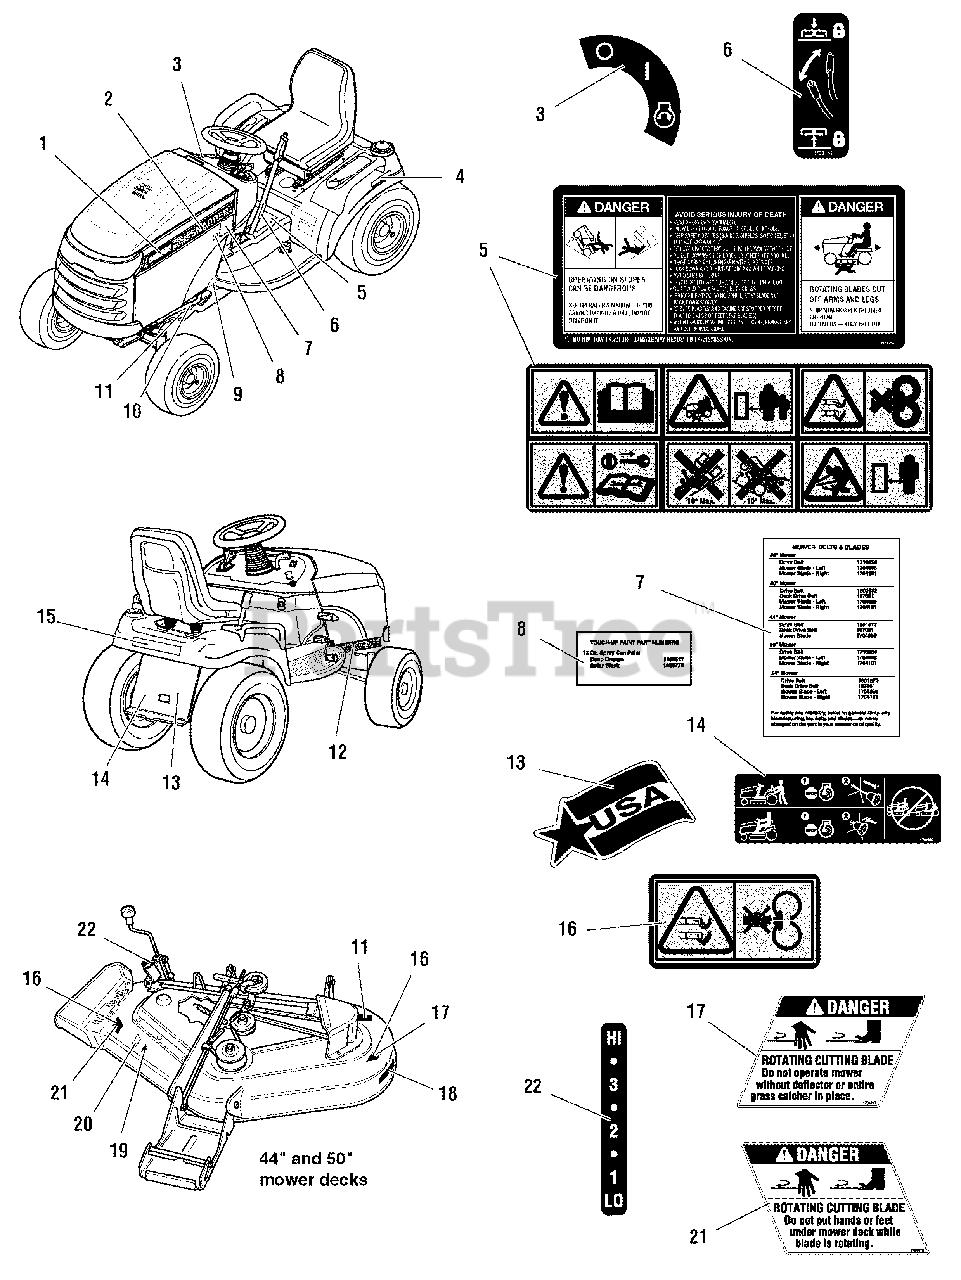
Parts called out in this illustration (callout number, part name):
1	DECAL, YT1644
1	DECAL, YT1844
1	DECAL, YT1850
1	DECAL, YT2050
2	DECAL, Hood Stripe, Snapper, LH
2	DECAL, Hood Stripe, Snapper, RH
3	DECAL, Ignition Switch Symbols, White/Black
4	DECAL, Automatic Control Traction
5	DECAL, Tunnel Cover, Danger Slopes/Blades
5	DECAL, Tunnel Cover, Danger Slopes/Blades, (Export)
6	DECAL, Lift Lever Symbols
7	DECAL, Drive Belts, Mower Blades
8	DECAL, Touch-Up Paint, Red
9	DECAL, Protective Sticker
10	* LABEL, Decibel, Power Mass
11	* DECAL, I.D. Plate
12	* DECAL, Patent
13	DECAL, USA Logo Stars & Stripe
14	DECAL, Transmission Release Valve
15	DECAL, Snapper
16	DECAL, Danger Rotating Blade Symbol
17	DECAL, Danger Do Not Put Hands/Feet in Mower
18	DECAL, Free Floating Mower, Silver
19	* DECAL, OPEI Certified
20	DECAL, 44", Silver on Black with Stripe
20	DECAL, 50", Silver on Black with Stripe
21	DECAL, Danger Do Not Operate Without Deflector
22	DECAL, Height of Cut
